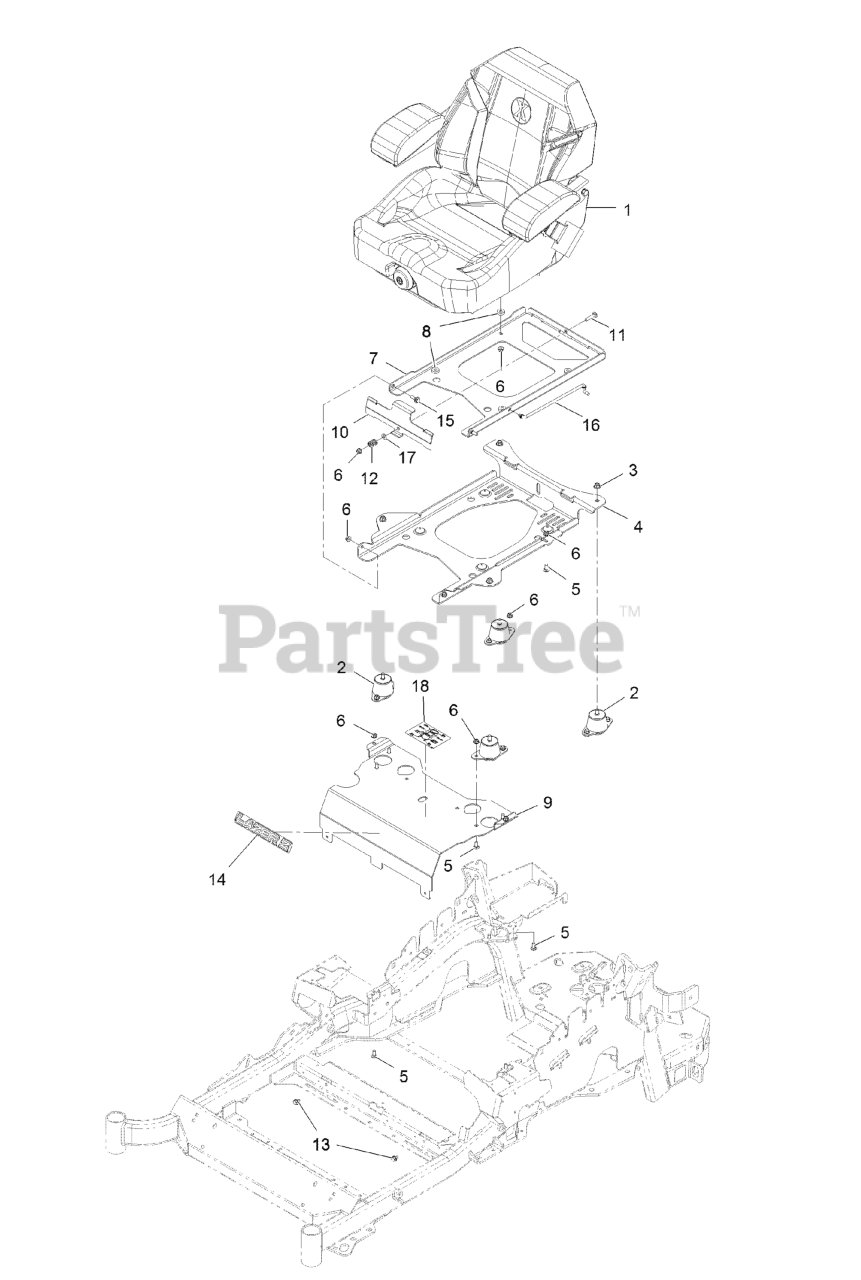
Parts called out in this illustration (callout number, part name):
1	KIT-SUSPENSION SEAT
2	ISOLATOR-SEAT
3	NUT-HF, NI
4	PLATE-TILT, SEAT SUPPORT
5	SCREW-CARR
6	NUT-HF, NI
7	PLATE-FRAME, SEAT
9	Panel-Front, Seat Mount
10	PLATE-LATCH, SEAT
11	BOLT-CARR
12	SPRING-COMPRESSION
14	DECAL, LAZER MODEL
15	SCREW-SHOULDER
16	ROD-PROP
17	WASHER-PLAIN
18	DECAL-SERVICE AID
